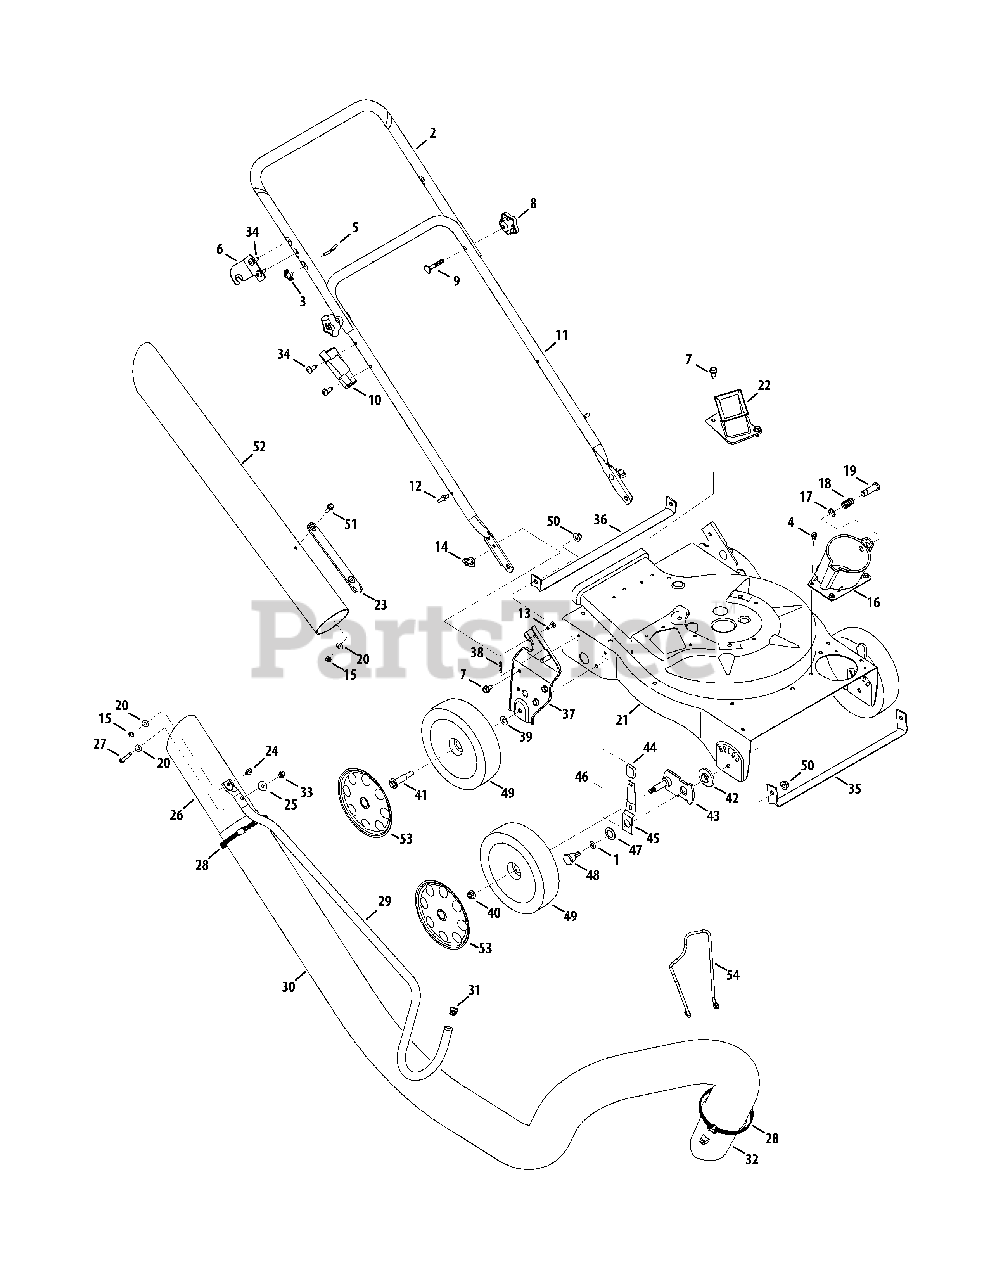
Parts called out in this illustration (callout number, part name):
1	Thrust Washer.375 ID x.70 OD
4	Screw, 1/4-20 x .500
6	Upper Handle Bracket
7	Hex Cap Screw 5/16-12 x.750
9	Carriage Bolt
10	Nozzle Handle Clip
13	Carriage Screw 1/4-20 x.75
14	Wing Nut 1/4-20
15	Hex Lock Nut, 1/4-20
16	Hose Base Adapter Assembly (Incl. Ref.# 17-19)
17	E Ring.500 Dia
18	Compression Spring
19	Clevis Pin
20	Flat Washer.271 ID x.630 OD
21	Upper Flail Housing
22	Chipper Chute Assembly
23	Chute Strap
26	Hose Nozzle
27	Hex Cap Screw 1/4-20 x 2.625
28	Adjustment Clamp
30	Vacuum Hose
31	Handle Plug
32	Hose Adapter, 173CC
33	Cap Lock Nut, 1/4-20
34	TT Screw, 5/16-18 x .750
35	Front Wheel Support Brace
36	Rear Wheel Support Brace
37	Handle Bracket Ass’y RH
37	Handle Bracket Ass’y LH
38	Cotter Pin
39	Bell Washer.401 ID x.870 OD
40	Flange Lock Nut, 3/8-16
41	Shoulder Screw 3/8-16
42	Height Adjustment Bearing
43	Pivot Arm Assembly
44	Height Adjustment Knob
45	Spring Lever
46	Height Lever Assembly (Incl. Ref.# 44-45)
47	Bell Washer.760 ID x.25 OD
48	Shoulder Screw,.750 x.500
49	Wheel, 8 x 2
50	Flange Lock Nut, 3/8-16
51	Screw, 1/4-20 x .75
52	Hose Extension
53	Hubcap, 8"
54	Tube Holder
